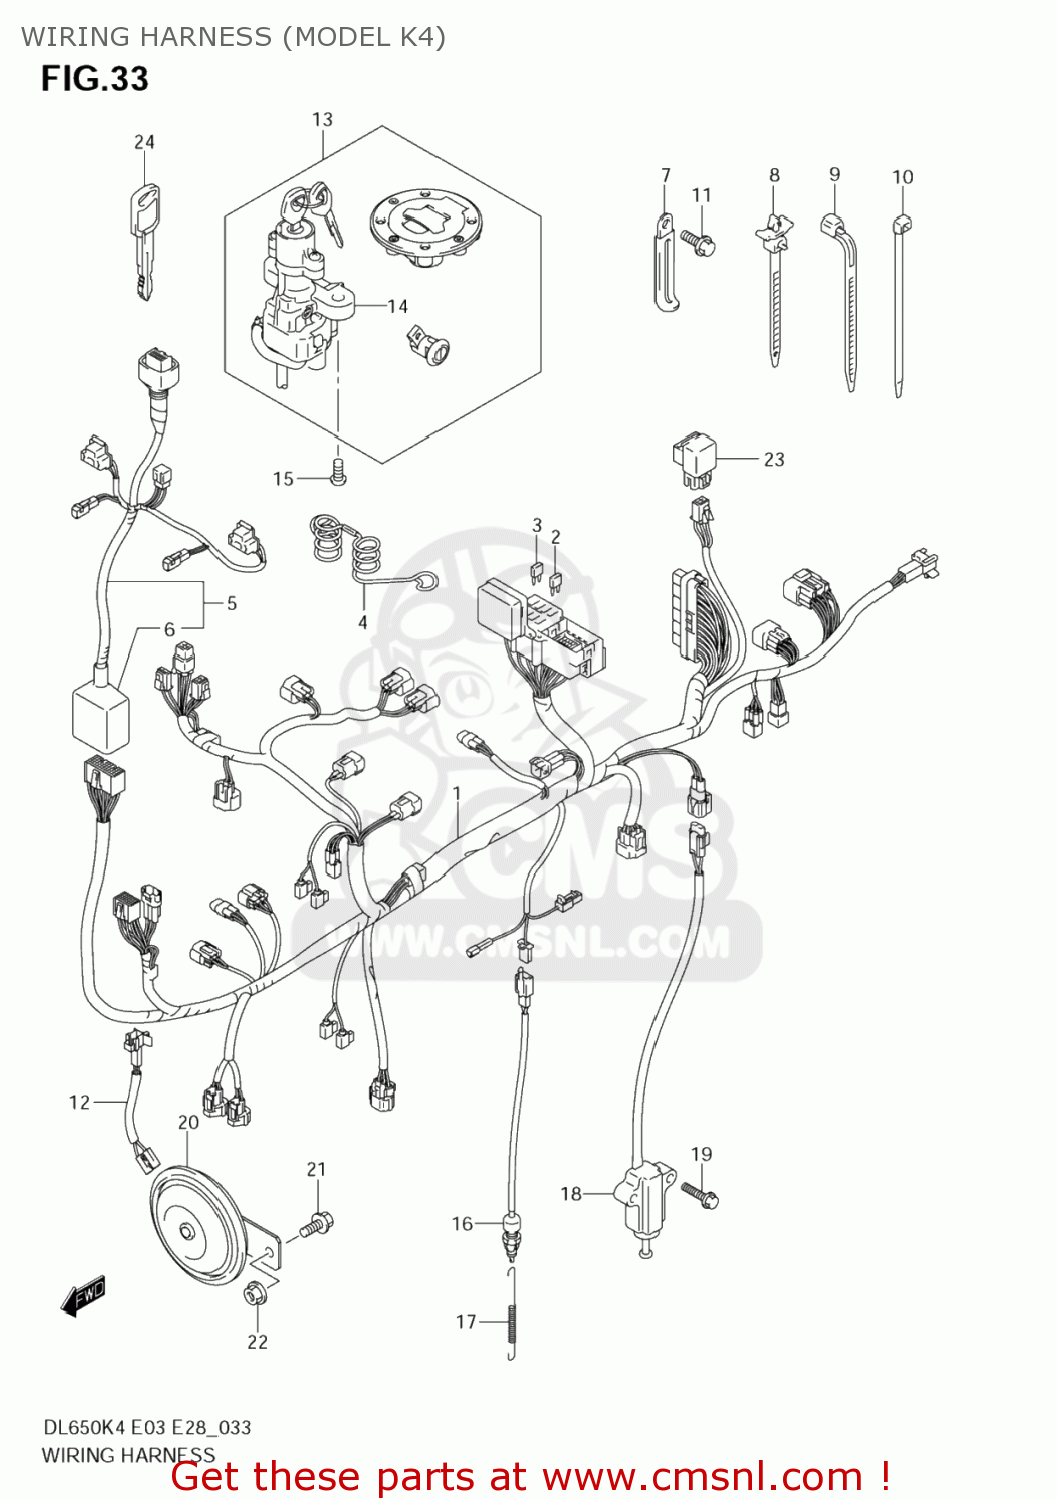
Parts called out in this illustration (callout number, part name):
1	HARNESS,WIRING NO.1
2	FUSE(10A)
3	FUSE(15A)
4	GUIDE,WIRING HARNESS
5	HARNESS,WIRING NO.2
6	COVER,CONNECTOR
7	CLAMP(L:45)
8	CLAMP(L:90)
9	CLAMP(L:125)
10	CLAMP(L:145)
11	BOLT
12	WIRE,HORN LEAD
13	LOCK SET
14	LOCK ASSY,STEERING
15	BOLT(8X20)
16	SWITCH ASSY,STOP LAMP
17	SPRING
18	SWITCH ASSY,SIDE STAND
19	BOLT
20	HORN ASSY
21	BOLT
22	NUT
23	RELAY ASSY
24	KEY,BLANK
